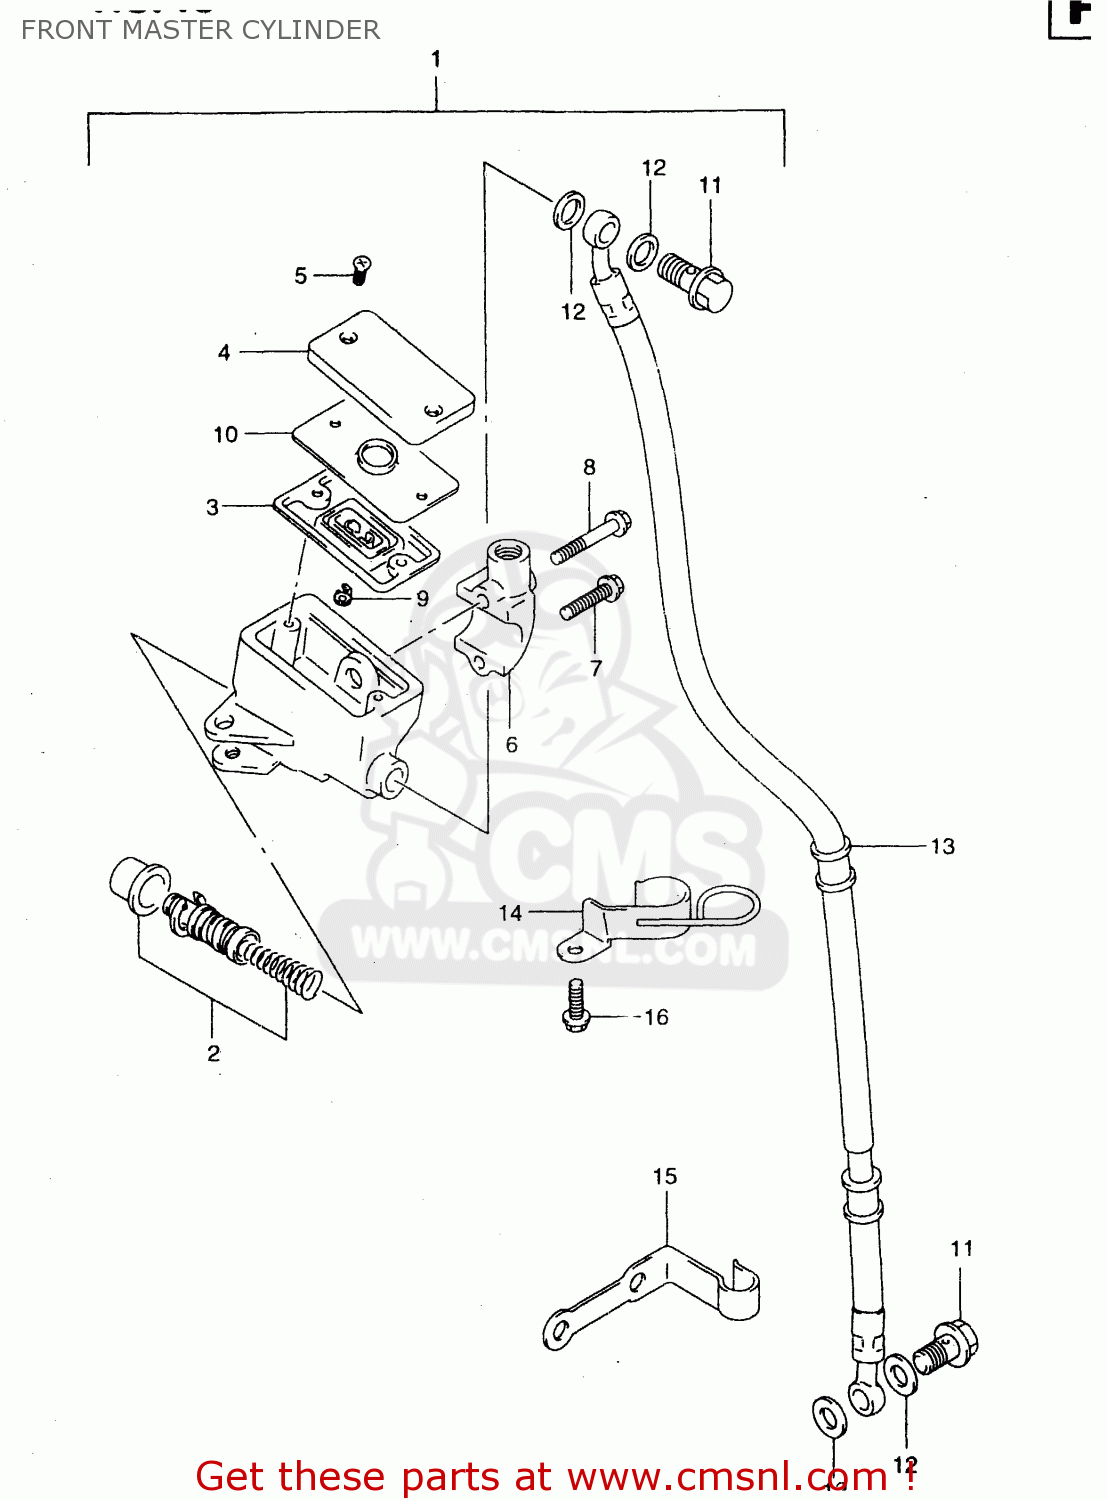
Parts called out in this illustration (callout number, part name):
1	CYLINDER ASSY,FR MASTER
2	PISTON/CUP SET
3	4
4	CAP
5	SCREW
6	HOLDER
7	BOLT(6X25)
8	BOLT(6X38)
9	PROTECTOR
10	PLATE,DIAPHRAGM
11	BOLT UNION
12	WASHER(10X15X1.5)
13	HOSE,FR BRAKE
14	CLAMP,FR BRAKE HOSE
15	CLAMP,BRAKE HOSE
16	BOLT
